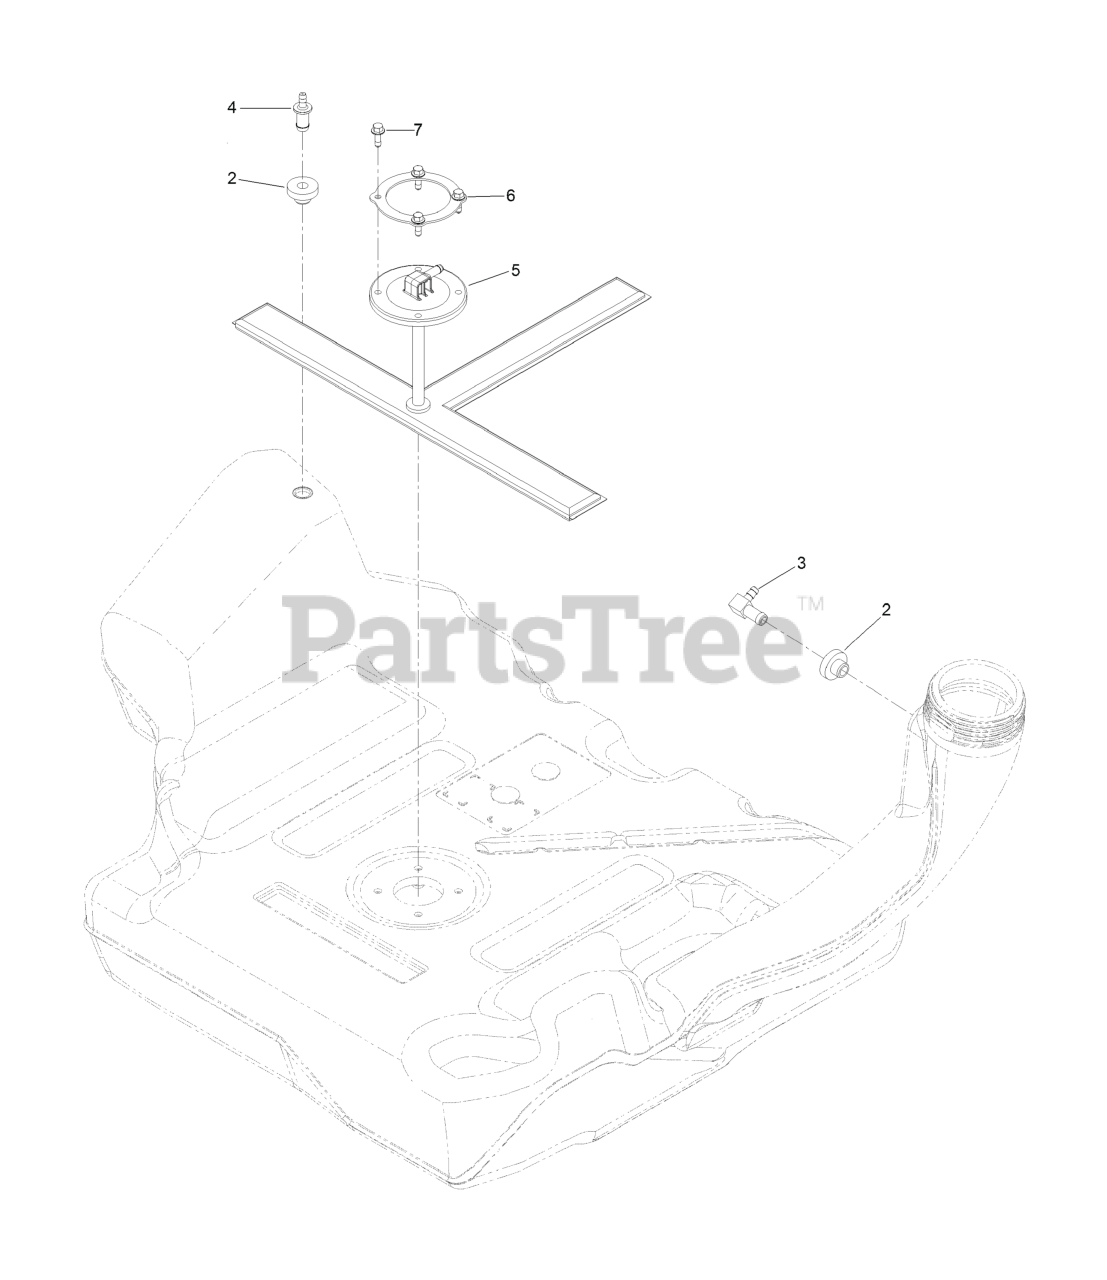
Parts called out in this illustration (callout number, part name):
2	BUSHING
3	FITTING-90 DEG
4	FITTING-ORIFICE, STRAIGHT
5	PICKUP-FUEL
6	RING-RETAINER
